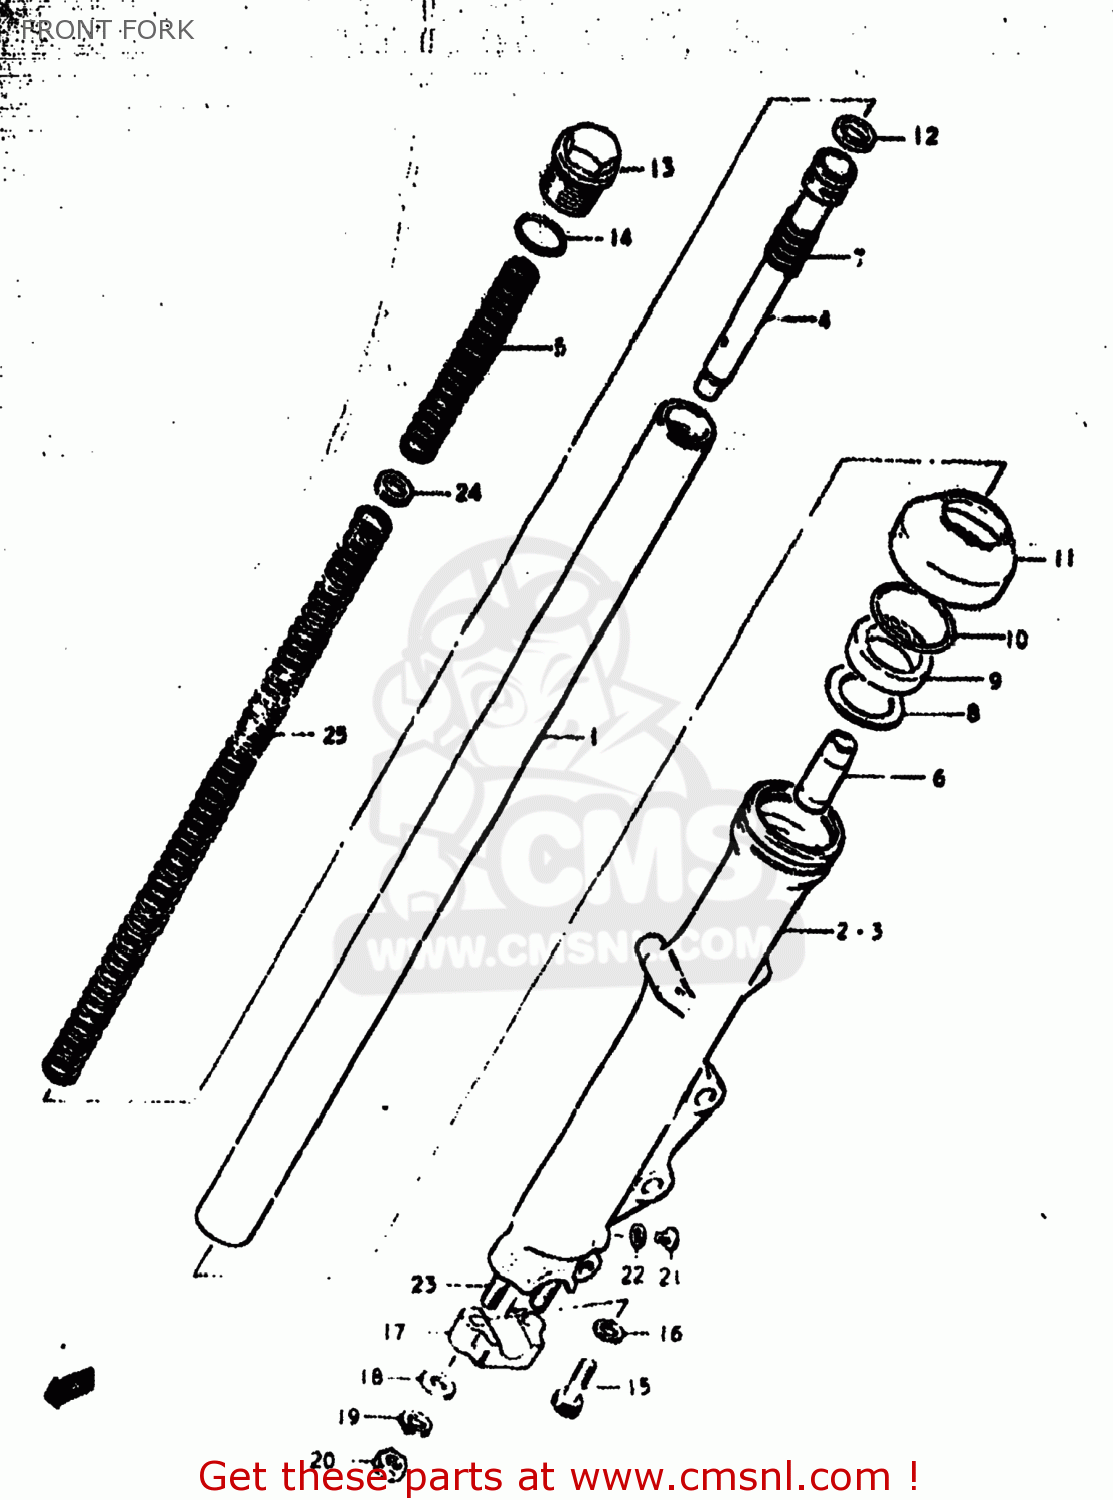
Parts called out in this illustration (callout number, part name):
0	DAMPER ASSEMBLY,LEFT
1	TUBE,FORK,INNER
2	TUBE,FORK,LEFT,OUTER
3	TUBE,FORK,OUTER,RIGHT
4	SEAT,FRONT FORK,UNDER
5	SPRING
6	PIECE,OIL LOCK
7	SPRING,FORK REBOUND
8	SPACER,SEAL
9	OIL SEAL,FRONT FORK
10	RING,OIL SEAL STOPPER
11	BOOT
12	RING
13	CAP,INNER TUBE
14	O RING
15	BOLT
16	GASKET (NAS)
17	HOLDER,AXLE
18	WASHER
19	LOCK WASHER
20	NUT
21	SCREW
22	GASKET (NAS)
23	STUD 8X25
24	WASHER
25	SPRING,FRONT FORK
